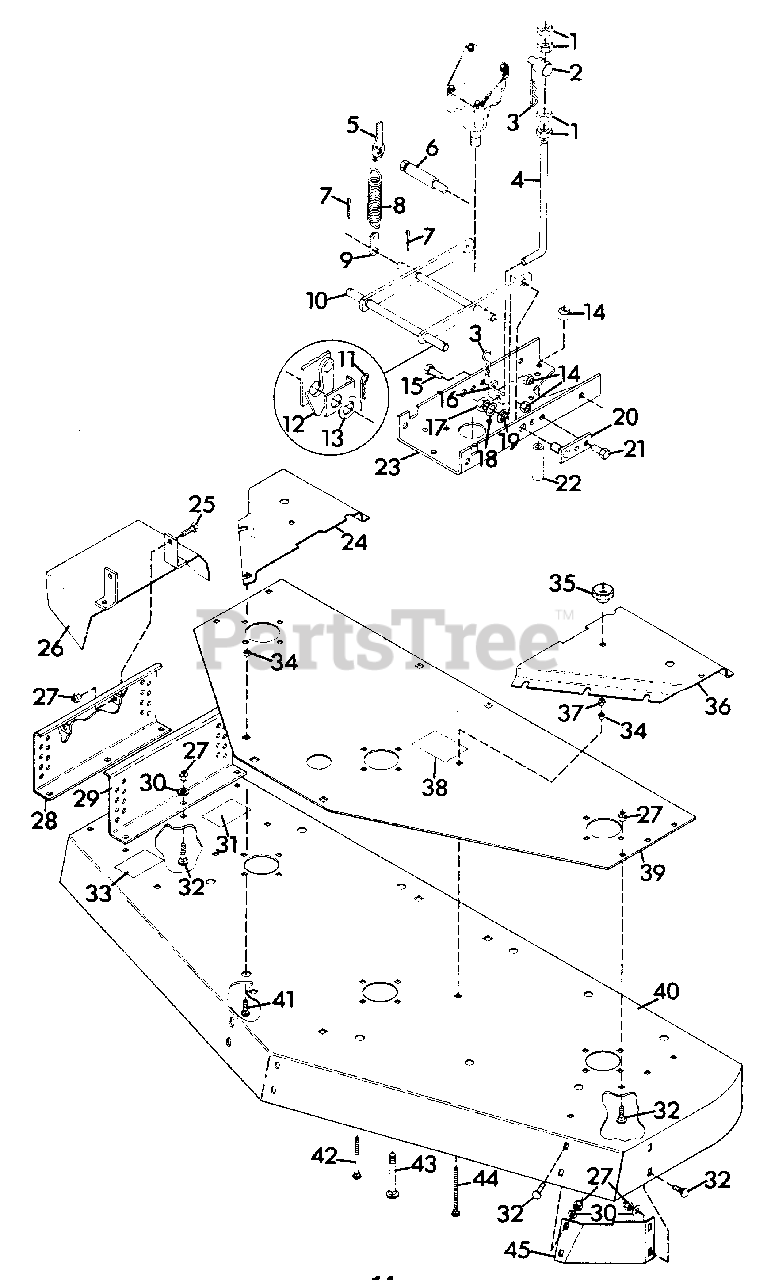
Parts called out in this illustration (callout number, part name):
1	Nut, Jam 1/2-13 Hex
2	Pivot, Mower Lift
3	Pin, Cotter Hair
4	Rod, Lift
5	Latch, Spring Assembly R.H.
5	Latch, Spring Assembly L.H.
6	Latch, Pin
7	Pin, Cotter .125x1.25
8	Spring, Ext. 7.625x1.50x.70 Rate
9	Strap
10	Weldment, Pivot Arm
11	Pin, Hair
12	Keeper, Mower Pivot
13	Washer, Flat .813x1.37x.100
14	Nut, Lock 1/2-13
15	Bolt, Hex 1/2-13x1.75
16	Bracket, Lift
17	Nut, Lock 3/4-10
18	Race, Bearing Thrust
19	Bushing, Nylon 76x1.0x.6 Flg.
20	Weldment, Pivot Anchor
21	Bolt, Hex 1/2-13x1.50
22	Spacer, .850x.546x2.18
23	Plate, Support
24	Cover, Belt R.H.
25	Bolt, Hex 3/8-16x1.25
26	Weldment, Discharge Chute
27	Nut, Lock 3/8-16
28	Weldment, 60" Hanger
29	Hanger, L.H.
30	Washer, Flat .406x.812x.065
31	Decal, Danger Hand
32	Bolt, 3/8-16x1.00 Rd Hd Sq Nk
33	Decal, Warning Eye
34	Nut, Jam 5/16-18 Hex
35	Knob
36	Cover, Belt L.H.
37	Nut, Lock 5/16-18
38	Decal, Belt Diagram
39	Plate, Deck Support
40	Weldment, 60" Deck
41	Bolt, Carriage 5/16-18x1.00
42	Bolt, Hex 5/16-18x3.50
43	Bolt, 1/2-13x3.50 Rd Hd Sq Nk
44	Bolt, 5/16-16x4.0 Rd Hd Sq Nk
45	Baffle, Front
